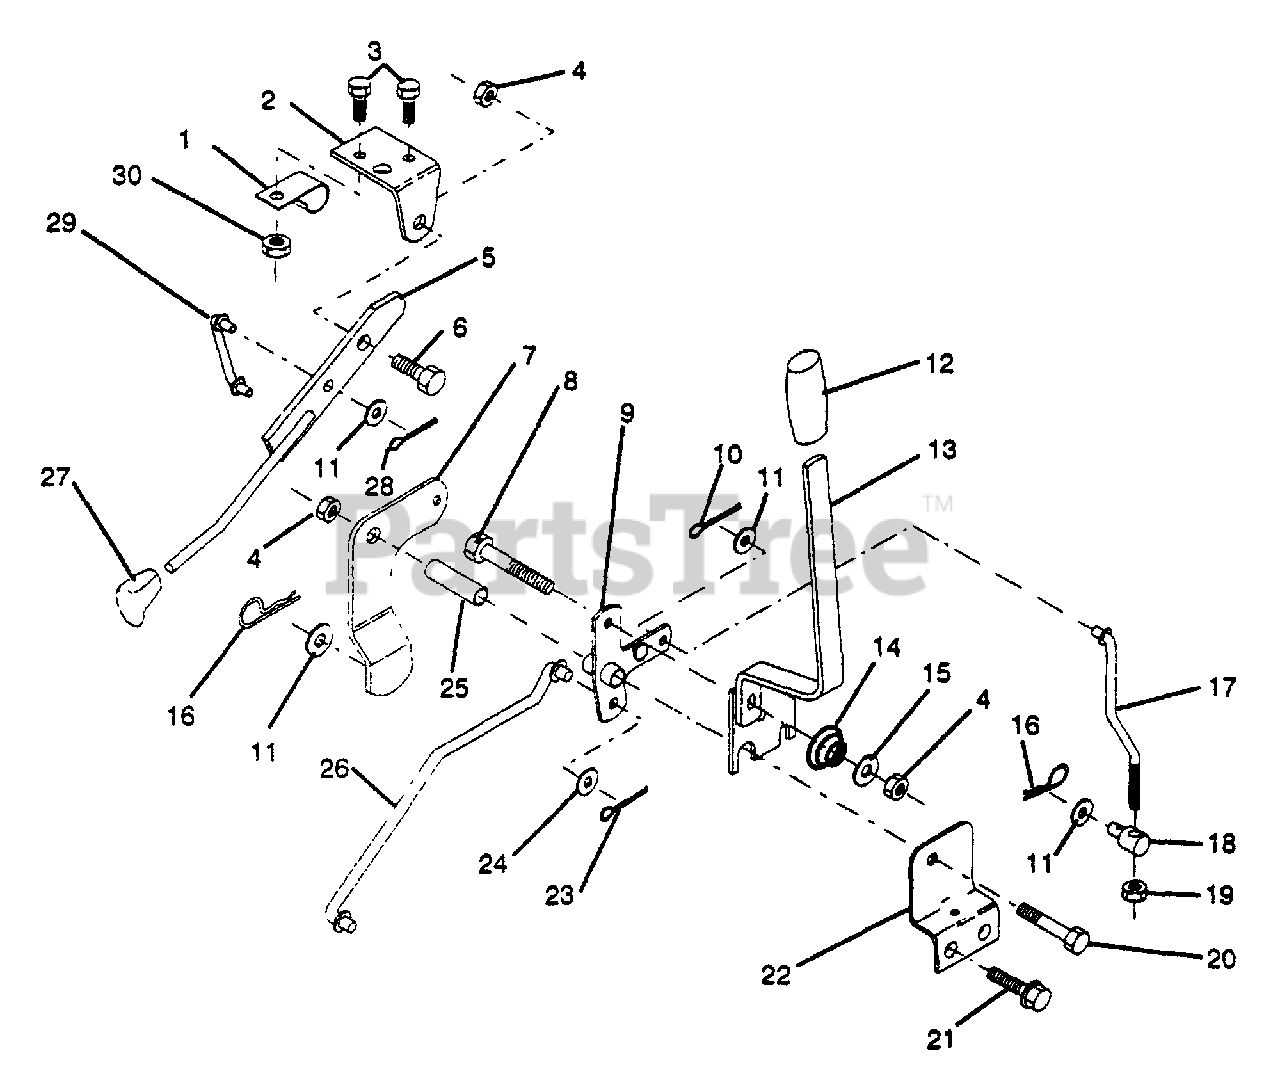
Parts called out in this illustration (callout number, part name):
1	Clip, Insulated
2	Bracket, Mower Clutch
3	Bolt, Fin. Hex 1/4-20 UNC x 1/2 Gr. 5
4	Nut, Crownlock 3/8-16 UNC
5	Assembly, Clutch Lever
6	Bolt, Shoulder
7	Assembly, Mower Clutch Arm
8	Bolt, Hex 3/8-16 UNC x 2-1/4
9	Assembly, Bellcrank Lift
10	Pin, Cotter 1/8 x 3/4
11	Washer, 13/32 x 13/16 x 16 Ga.
12	Grip, Handle
13	Assembly, Lift Handle
14	Spring, Compression
15	Washer 13/32 x 3/4 x 12 Ga.
16	Retainer, Spring
17	Link, Front Lift
18	Trunnion, Threaded 3/8-16
19	Nut, Hex Jam 3/8 x 16 UNC
20	Bolt, Fin. Hex 3/8-16 UNC x 2-3/4
21	Screw, Hex Thdrol. 5/16-18 x 1/2
22	Bracket, Mower Height
23	Pin, Cotter 1/8 x 1
24	Washer 17/32 x 1 x 16 Ga.
25	Tube, Spacer
26	Rod, Mower Lift
28	Pin, Cotter 3/32 x 3/4
29	Link, Mower Clutch
30	Nut, Crownlock 1/4-20
